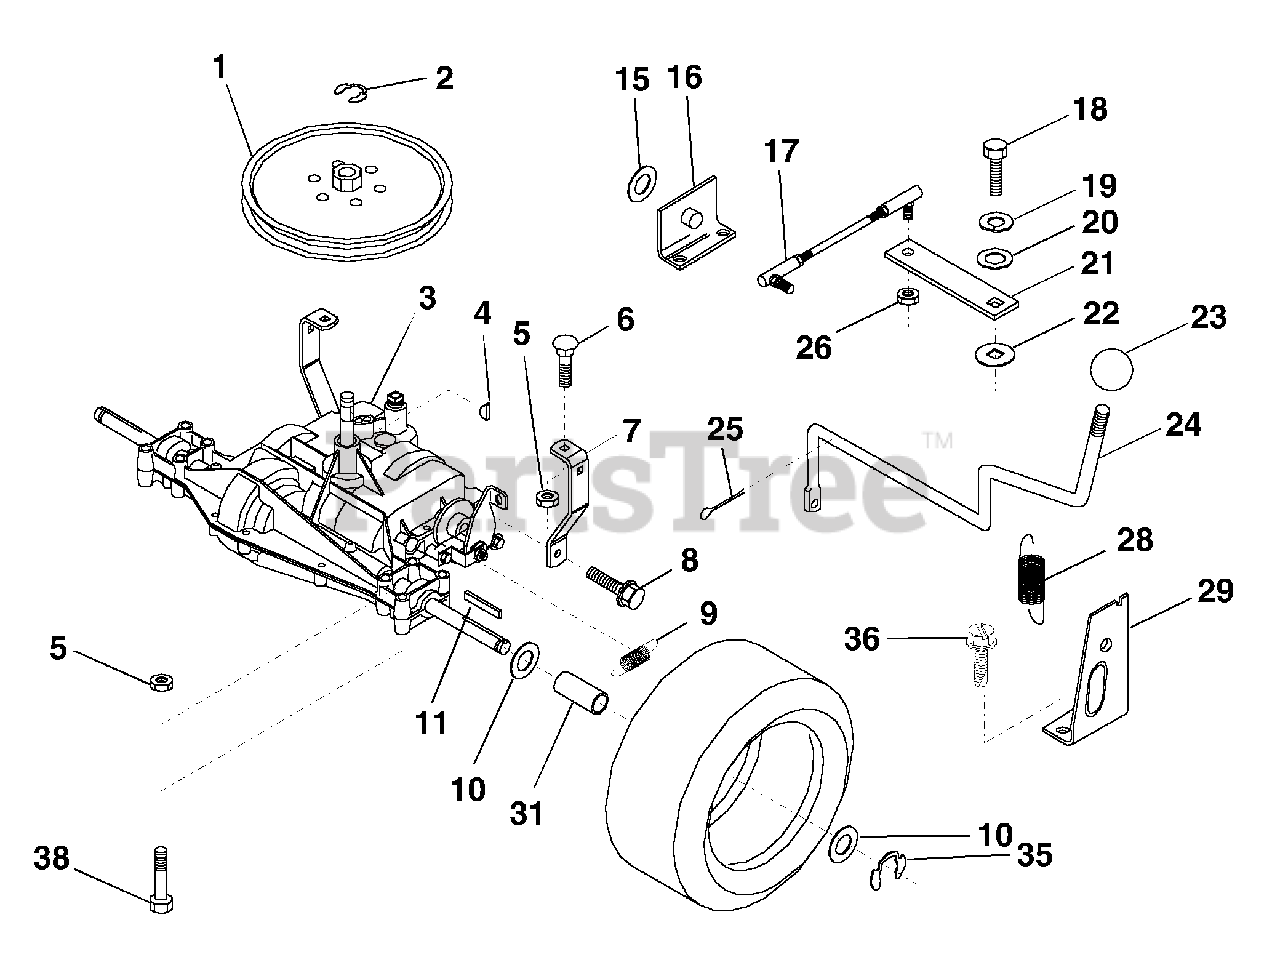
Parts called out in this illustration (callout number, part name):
2	Ring, Retainer
4	Key, Woodruff #9
5	Nut, Crownlock 5/16-18
6	Bolt, Carriage 5/16-18 UNC x 3/4
7	Strap, Torque
8	Screw 5/16-18 x 3/4
9	Spring, Brake
10	Washer 25/32 x 1-1/4 x 16 Ga.
11	Key, Square
15	Washer 17/32 x 1 x 16 Ga.
16	Support Handle Shift LH
17	Link, Shift
18	Bolt, Fin Hex 1/4-28 UNF x 3/4 Gr. 8
19	Washer, Lock 1/4
20	Washer 9/32 x 3/4 x 10 Ga.
21	Arm, Shift
22	Washer, Shift Plate
23	Knob, Rd 1/2-13
25	Pin, Cotter 1/8 x 1
26	Locknut 5/16-24 UNF
28	Extension, Spring
29	Support Handle Shift RH
31	Spacer Axle
36	Screw, Thd Cut 1/4-20 x 1/2
38	Bolt Hex Flghd 5/16-18 x Gr. 5
